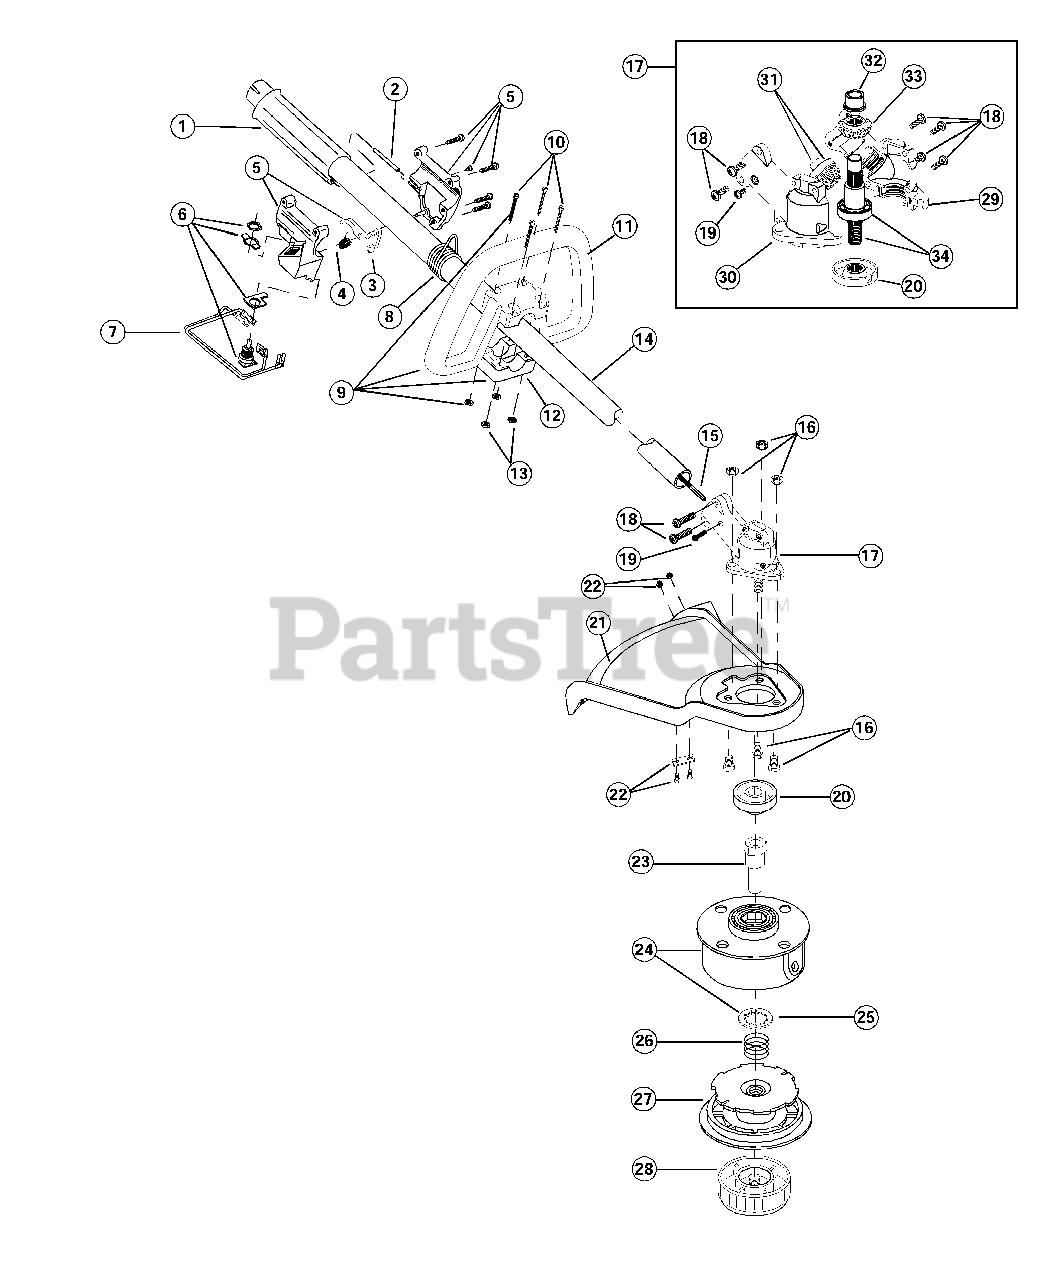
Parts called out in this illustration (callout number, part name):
2	Throttle Cable Assembly
3	Throttle Trigger
4	Throttle Trigger Spring
5	Throttle Trigger Assembly
6	Switch Assembly
7	Wire Lead Assembly
8	Shoulder Harness Clamp
9	Loop Handle Assembly
11	Loop Handle
12	Bottom Clamp
14	Drive Shaft Housing Assembly
15	Drive Shaft
16	Shield Mount Screw Assembly
17	2 piece Gearbox Assembly
18	Gearbox Mounting Hardware
19	Anti-Rotation Screw
20	Blade Driver
21	Shield and Blade Assembly
22	Blade Assembly
23	Spool Shaft
24	Outer Spool & Eyelet Assembly
25	Retainer
26	Spring
28	Bump Head Knob Assembly
29	Left Housing
30	Right Housing
31	Pinion Gear Assembly
32	Output Shaft Bushing
33	Output Shaft Gear
34	Output Shaft Assembly
